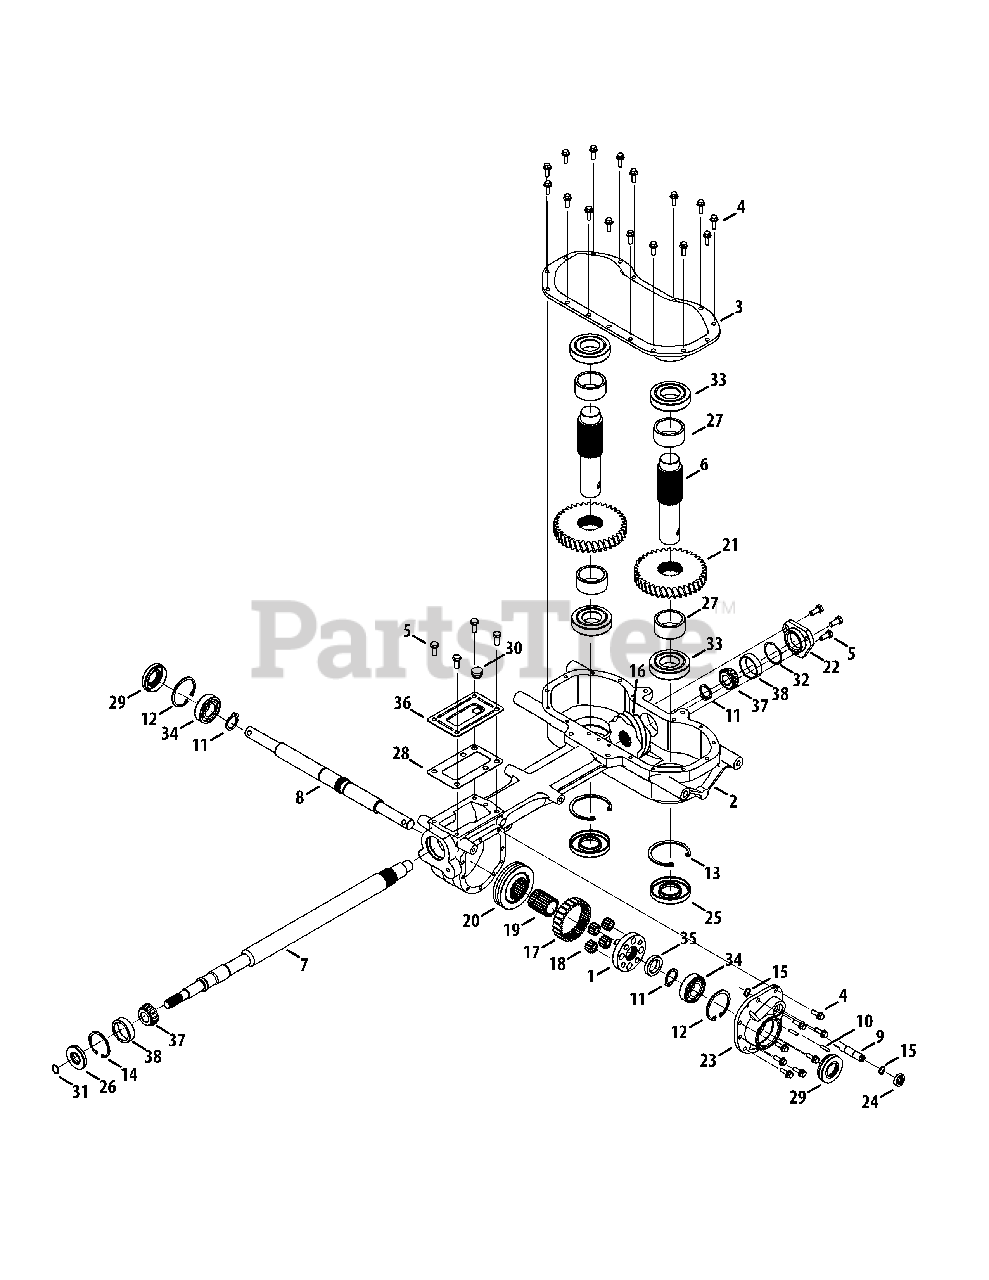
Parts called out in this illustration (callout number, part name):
1	Planetary Carrier
2	Housing Assembly
3	Cover
4	Hex Flange Screw, 1/4-20, .75, Gr5
5	Hex Head Screw, 5/16-18 x .75
6	Tine Shaft
7	Shaft, Worm
8	Shaft, Wheel
9	Shaft, Drive
10	Pin, Dowel, 3/16 x 3/4
11	Snap Ring, 1.00 Shaft Dia.
12	Retaining Ring
13	Retaining Ring
14	Retaining Ring, Int
15	Snap Ring
16	Gear, 7t
17	Gear, 48t
18	Gear, 12t
19	Gear, 24t
20	Gear, 61t
21	Gear, 38t
22	Bearing Cover
23	Wheel Cover
26	Oil Seal, .75 x 1.783
27	Spacer, 1.625 x 2.125 x 1.010
28	Gear Housing Gasket
29	Oil Seal, 1.00 SHF x 2.00 BORE
30	Rubber Oil Plug
31	Ring, Wire
32	Washer, Flat, 1.50 x 1.75 x .062
32	Washer, Flat, 1.50 x 1.75 x .005
32	Washer, Flat, 1.50 x 1.75 x .03
32	Washer, Flat, 1.50 x 1.75 x .010
33	Bearing Ball
34	Ball Bearing, 1 x 52 x 15 x 6205-1
35	Spacer, 1.010 x 1.500 x 0.175
36	Transmission Cover
37	Cone Bearing
38	Cup Bearing
